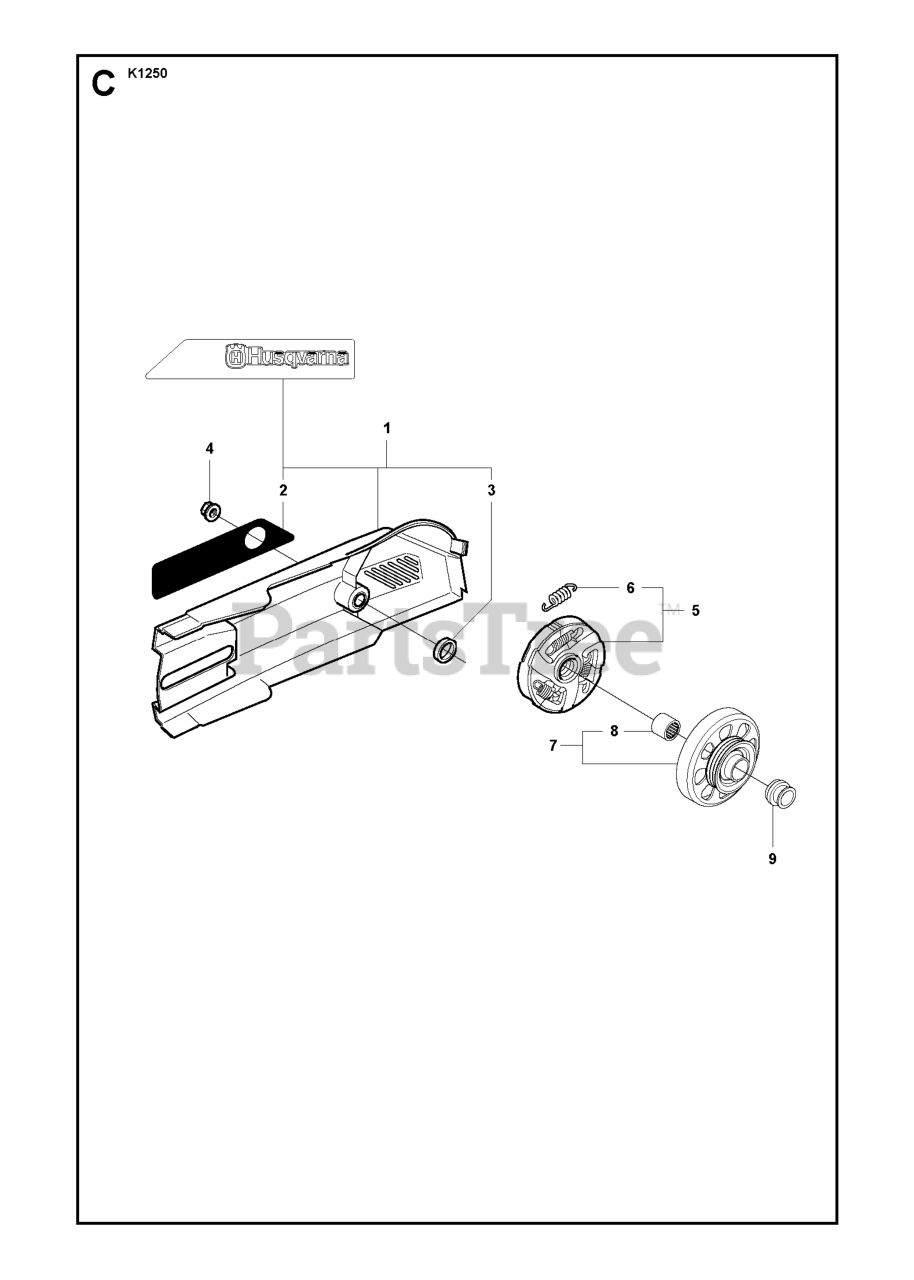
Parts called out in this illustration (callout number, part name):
1	BELT GUARD, REAR ASSY
4	NUT M8 FLANGE
5	CLUTCH CPL
6	CLUTCH SPRING
7	DRIVE SPROCKET 14"
7	WHEEL
7	DRIVE SPROCKET 16"
7	CLUTCH DRUM 14"
8	SUPPORT BUSHING
9	SPACER SLEEVE
